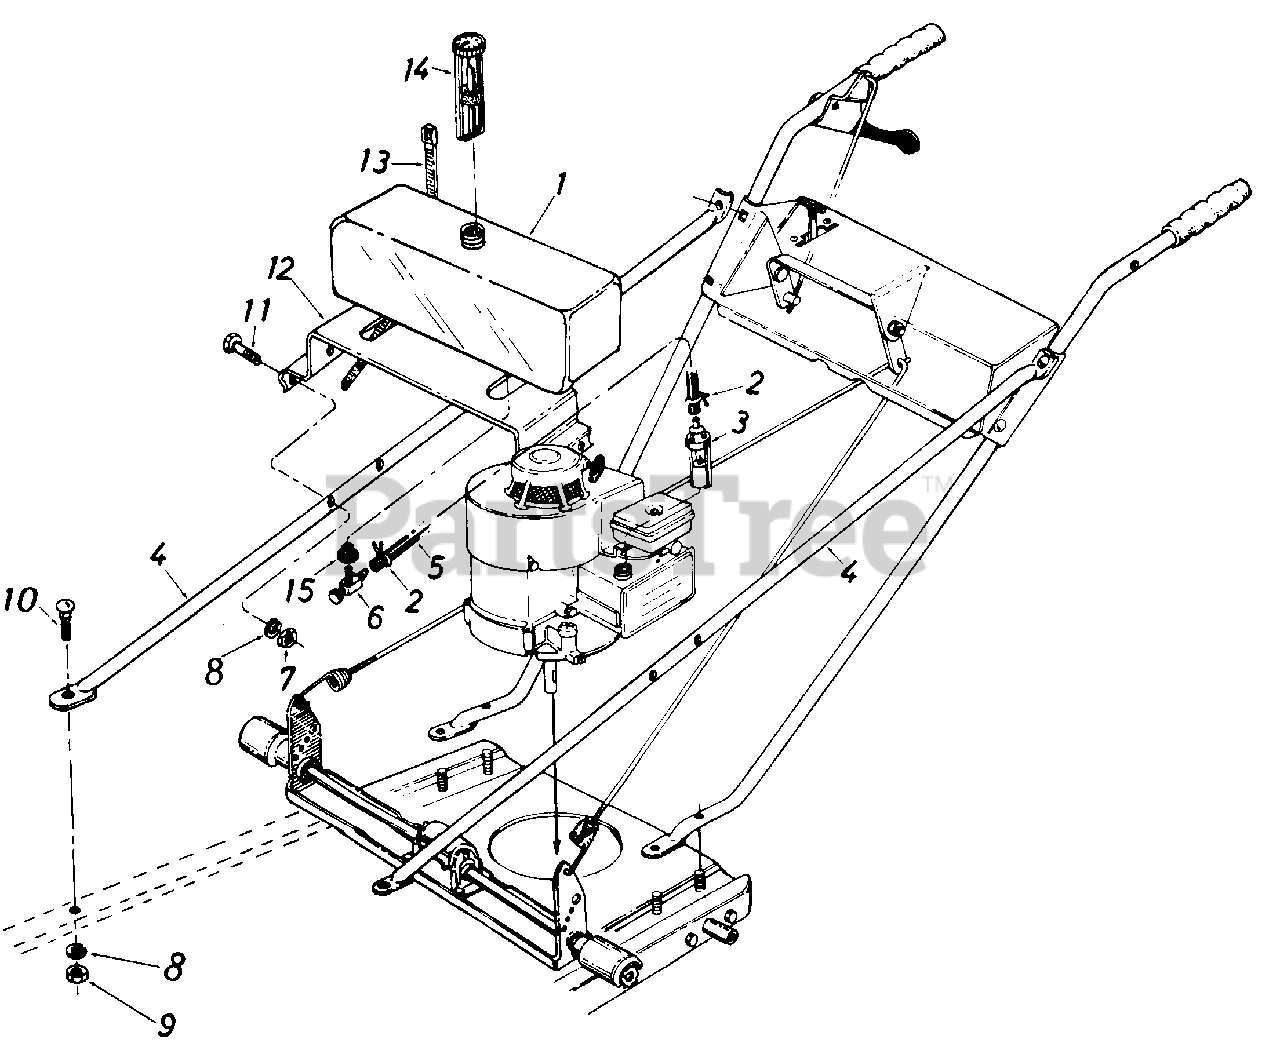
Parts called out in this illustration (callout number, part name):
2	CLAMP-HOSE 3/8
3	VALVE-FUEL CONTROL
4	STRUT-HI WHL
5	FUEL LINE-15IN
6	VALVE-SHUT OFF
7	NUT-5/16-24
8	WASHER-LOCK-5/16
9	NUT-HEX 5/16-18
10	BOLT-CARRIAGE 5/16-18 X .62
11	SCREW-HEX 5/16-24 X 1.25
12	BRACKET-GAS TANK MTG
13	TIE-CABLE
14	GAUGE-GAS
15	BUSHING
